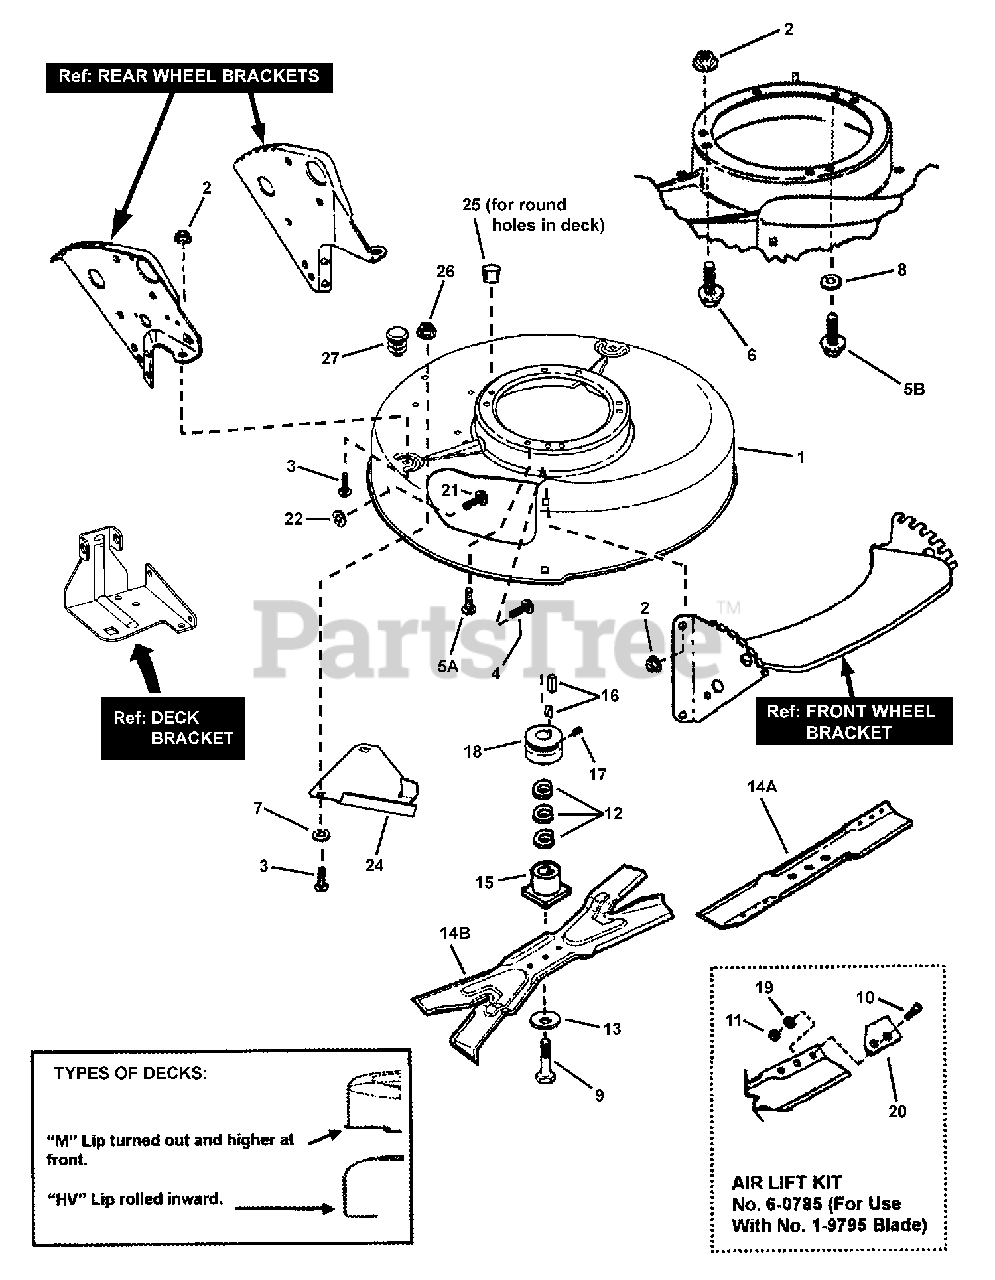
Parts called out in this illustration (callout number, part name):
1	* DECK, Mower (incl. painted "HV" Deck w/Wheel Brackets & Decals)
1	* ASSEMBLY, Non-Adjustable Air, 21" Deck
2	NUT, 5/16-18 Hex Flange Lock, GR 5
3	BOLT, 5/16-18 x 1/2", Short Neck Carriage, GR 5
4	BOLT, 5/16-18 x 1-1/8" Short Neck Carriage, GR 5
5A	SCREW, 3/8-16 x 1" Self-Tapping
5B	SCREW, 5/16-24 x 1" Hex Head Cap GR5
6	BOLT, 5/16-18 x 1-1/2" Hex Flange Lock, GR5
7	WASHER, 7/16" Flat
8	WASHER, .32 x .58 x .08 Split Lock
9	SCREW, 3/8-24 x 2" Hex Head Cap, GR 5
10	SCREW, 5/16-24 x 21/32" Oval Head Machine
11	NUT, 5/16-24 Hex, GR5
12	1/16" THICK SPACER, Blade Hub
13	WASHER, Cone
14A	BLADE, Cutter (Standard Lift)
14B	BLADE, 21" Ninja (Quad Edge)
15	HUB, Blade Drive 25mm I.D.
15	HUB, Blade Drive 7/8"
16	KEY, #505 Hi-Pro
16	KEY, #HP-506 Hi-Pro
17	SCREW, 5/16-18 Hex Socket Head
18	PULLEY-Engine (25mm I.D. x 2-1/8 O.D.)
18	PULLEY, Engine (1" I.D. x 2.275" O.D.)
19	WASHER, 5/16" Internal Tooth Lock
20	AIR LIFT
21	BOLT, 5/16-18 x 3/4" Short Neck Carriage GR5
22	RETAINER, 5/16" Bolt
24	COVER, Belt (Baffle)
25	PLUG, 5/16" Hole
26	NUT, 5/16-18 Hex Flange Lock GR5
27	PLUG, Hole, Polyethylene
60785	KIT, Air Lift
